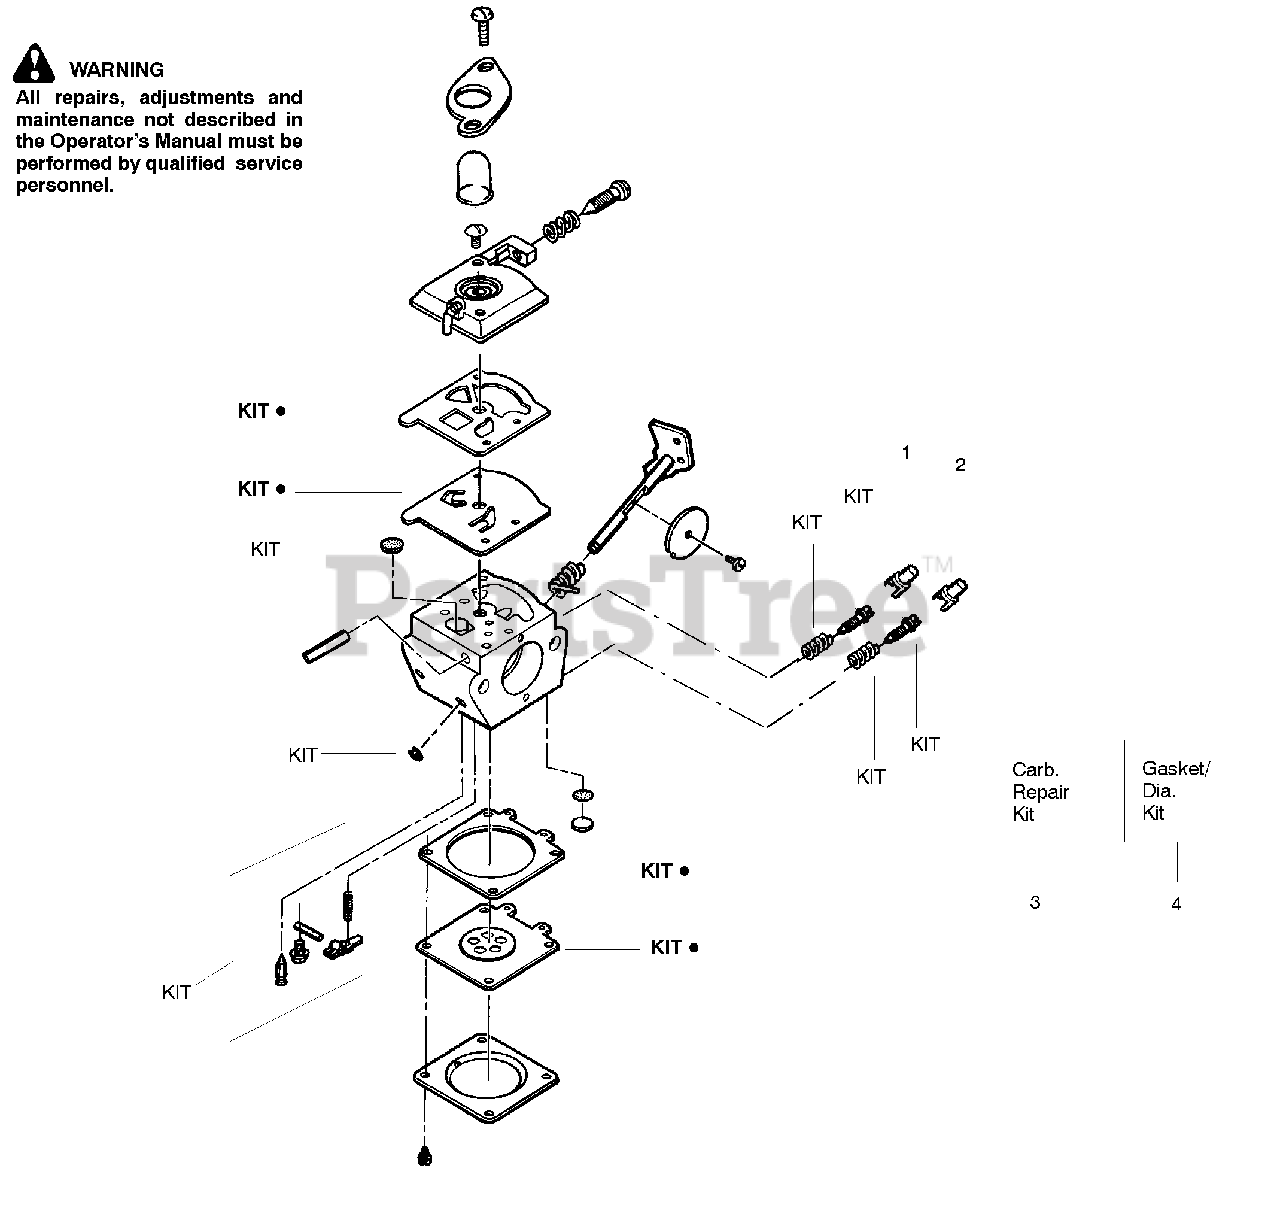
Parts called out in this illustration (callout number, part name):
1	Limiter Cap-Low (tan)
2	Limiter Cap-High (brown)
3	Carburetor Repair Kit ( KIT = CONTENTS)
4	Gasket/Diaphragm Kit ( • = CONTENTS)
